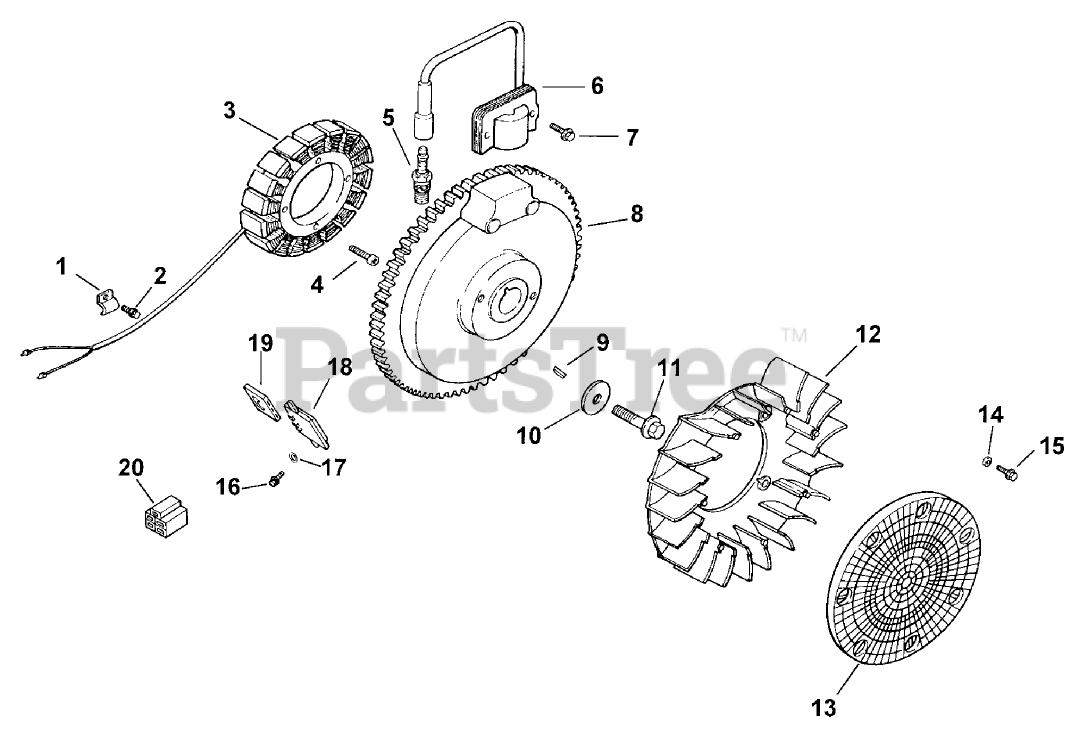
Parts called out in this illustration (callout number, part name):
1	Clip
2	Screw
3	Bracket-Wire, Stator
4	Screw
5	Spark Plug
6	Module, ignition
7	Screw
8	Flywheel
9	Key
10	Washer
11	Screw
12	Fan
13	Screen-Grass (Only On: 72042, 72063, 72062, 72043)
14	Spacer-Fan
15	Screw
16	Screw
17	Washer-Lock (Only On: 72042, 72063, 72062, 72043)
18	Rectifier-Regulator (Only On: 72042,72043,72062,72063)
19	Connector
20	Connector
